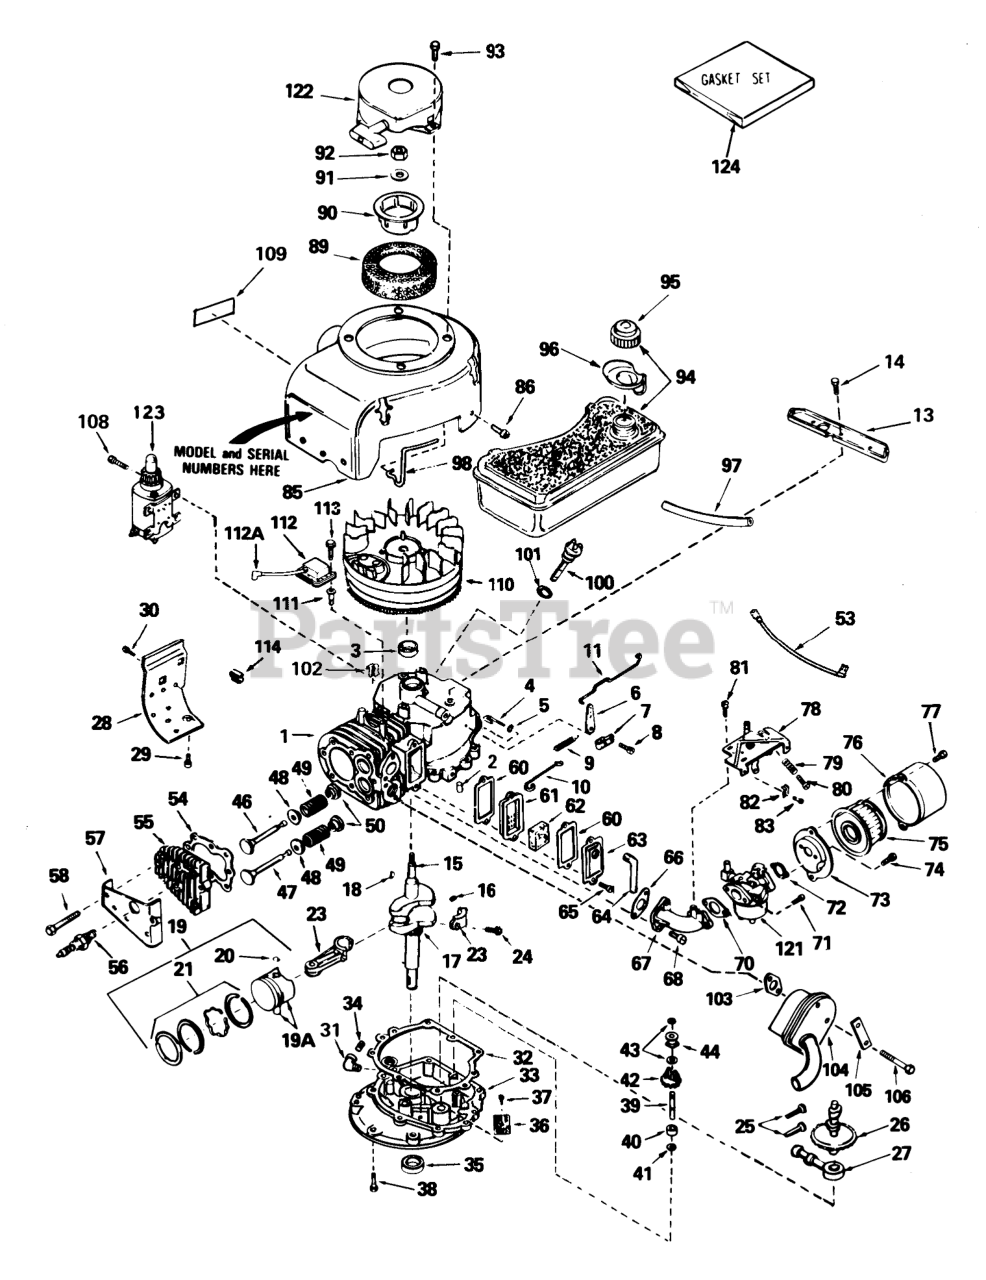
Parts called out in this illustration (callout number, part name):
1	Cylinder Assy., (Incl. Ref. #2, 3, 100 & 101)
2	Pin-Dowel
3	Oil Seal
4	Rod, Governor (Incl. Ref. #5)
5	Washer-Flat
6	Lever-Governor
7	Clamp-Lever, Governor
8	Screw
9	Spring Governor
10	Link Governor Spring
11	Link Governor
13	Bracket-Blower Housing
14	Screw (1/4-20x19/32)
15	Crankshaft Assy. (Incl. Ref. #16 & 17)
16	Pin, Groove
17	Gear-Crankshaft
18	Key-Flywheel
19	Piston, Pin & Ring Assy., (Std.) (Incl. Ref. #19A, 20 & 21 )
19	Piston, Pin & Ring Assy., (.010 oversize) (Incl. Ref. #19A, 20 & 21 )
19	Piston, Pin & Ring Assy., (.020 oversize) (Incl. Ref. #19A, 20 & 21 )
19A	Piston & Pin Assy., (Std.) (Incl. Ref. #20)
19A	Piston & Pin Assy., (.010 oversize) (Incl. Ref. #20)
19A	Piston & Pin Assy., (.020 oversize) (Incl. Ref. #20)
20	Ring-Retaining, Piston Pin
21	"O"Ring
21	Ring Set (.010" OS)
21	Ring Set (.020" OS)
23	Rod Assy., Connecting (Incl. Ref. #24)
24	Bolt, Connecting Rod
25	Lifter-Valve
27	Pump, Oil
28	Extension-Blower Hsng.
30	Screw
31	Elbow, 90deg. Street, 1/4-18 thread (Can be purchased locally)
32	Gasket-Cover, Cylinder
33	Flange, Mounting (Incl. Ref. #34 thru 37, 39 & 41)
34	Plug-Drain, Oil (SQH 1/4-18)
35	Seal-Oil
36	Screen-Oil Filter
38	Screw (1/4-20 x 1-1/4)
39	Shaft, Governor
40	Spacer Assy., Governor (Incl. Ref. #41)
41	Washer-Flat
42	Gear Assy., Governor (Incl. Ref. #41)
43	Ring-Retaining
44	Spool-Governor
46	Valve, Intake (Std.) (Incl. Ref. #50)
46	Valve, Intake (1/32" oversize) (Incl. Ref. #50)
47	Valve, Exhaust (Std.) (Incl. Ref. #50)
47	Valve, Exhaust (1/32" oversize) (Incl. Ref. #50)
48	Cap-Spring, Valve
49	Spring-Valve
50	Keeper-Spring, Valve
53	Wire-Ground
54	Gasket-Cylinder Head
55	Head, Cylinder (Incl. 3 of Ref. #58)
56	Plug, Spark (J17LM or equiv.)
56	Plug, Spark (Champion RCJ-8)
57	Cover-Head, Cylinder
58	Screw (5/16-18 X 2-1/2)
60	Gasket-Breather
61	Body-Breather
62	Element-Breather
63	Cover-Valve
64	Tube-Breather
66	Gasket-Intake
67	Pipe-Intake
68	Screw (T-30, 5/16-18x1-3/32)
70	Gasket
71	Screw-Hex Hd.
72	Gasket
73	Bracket
74	Screw (10-32 x 1/2)
75	Element
76	Body-Air Cleaner
78	Control Assy., Speed (Incl. Ref. #79 & 80)
79	Spring-Compression
80	Screw
81	Screw (10-24 x 9/16)
82	Conduit
83	Screw (10-32 x 3/8)
85	Housing-Blower
89	Screen-Starter
90	Cup-Starter
91	Washer-Belleville
94	Tank Assy., Fuel (Incl. Ref. #95)
95	Cap-Fuel
96	Deflector-Fuel
97	Line-Fuel (8.62)
98	Clamp, Tank Holdown
100	Dipstick, Oil (Incl. Ref. #101)
101	Gasket
102	Clip-Wire
103	Gasket Exhaust
104	Muffler
105	Plate-Locking
106	Screw Hex Hd.
108	Screw
109	Decal-Instruction
110	Flywheel
111	Stud
112	Solid State
112A	Cover-Spark Plug
113	Screw
114	Clip, Spring
121	Carburetor (Incl. Ref. #70)
122	tarter-Rewind
123	Tine Shaft
124	Gasket Set
